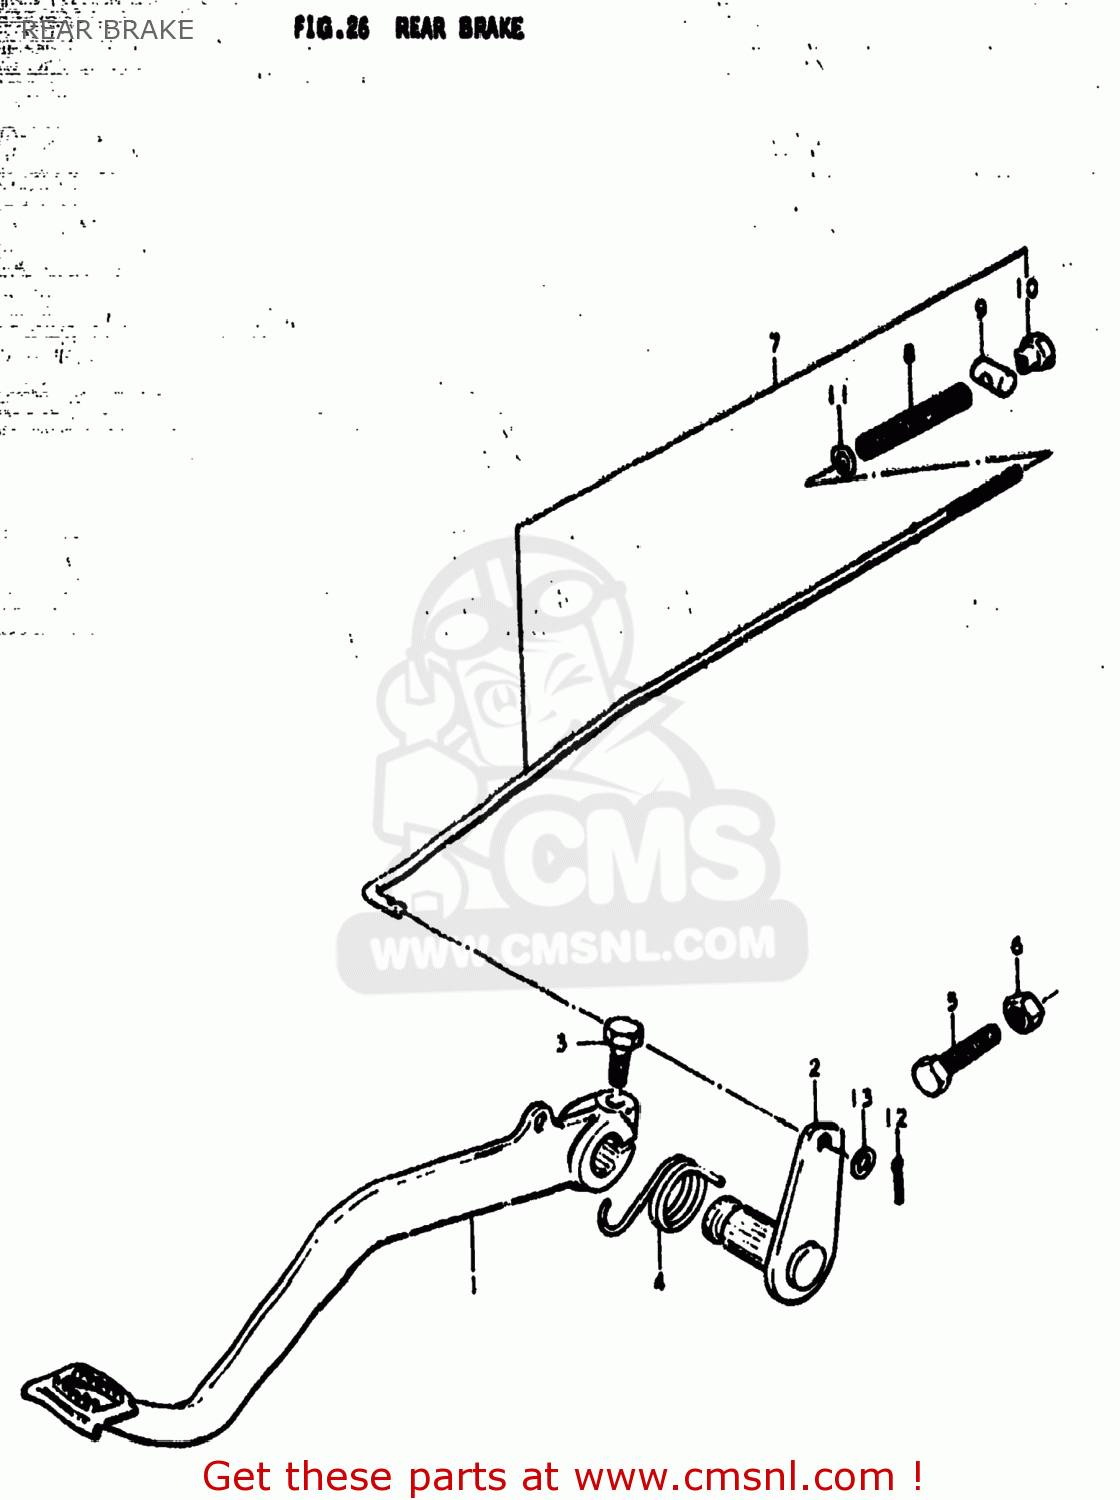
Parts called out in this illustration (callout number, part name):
1	PEDAL,BRAKE
2	ARM,BRAKE PEDAL ROD
3	BOLT
4	SPRING
5	BOLT(6X23)
6	NUT
7	ROD ASSY,RR BRAKE
8	SPRING
9	PIN(11X18)
10	NUT
11	WASHER
12	PIN 20X20
13	WASHER
